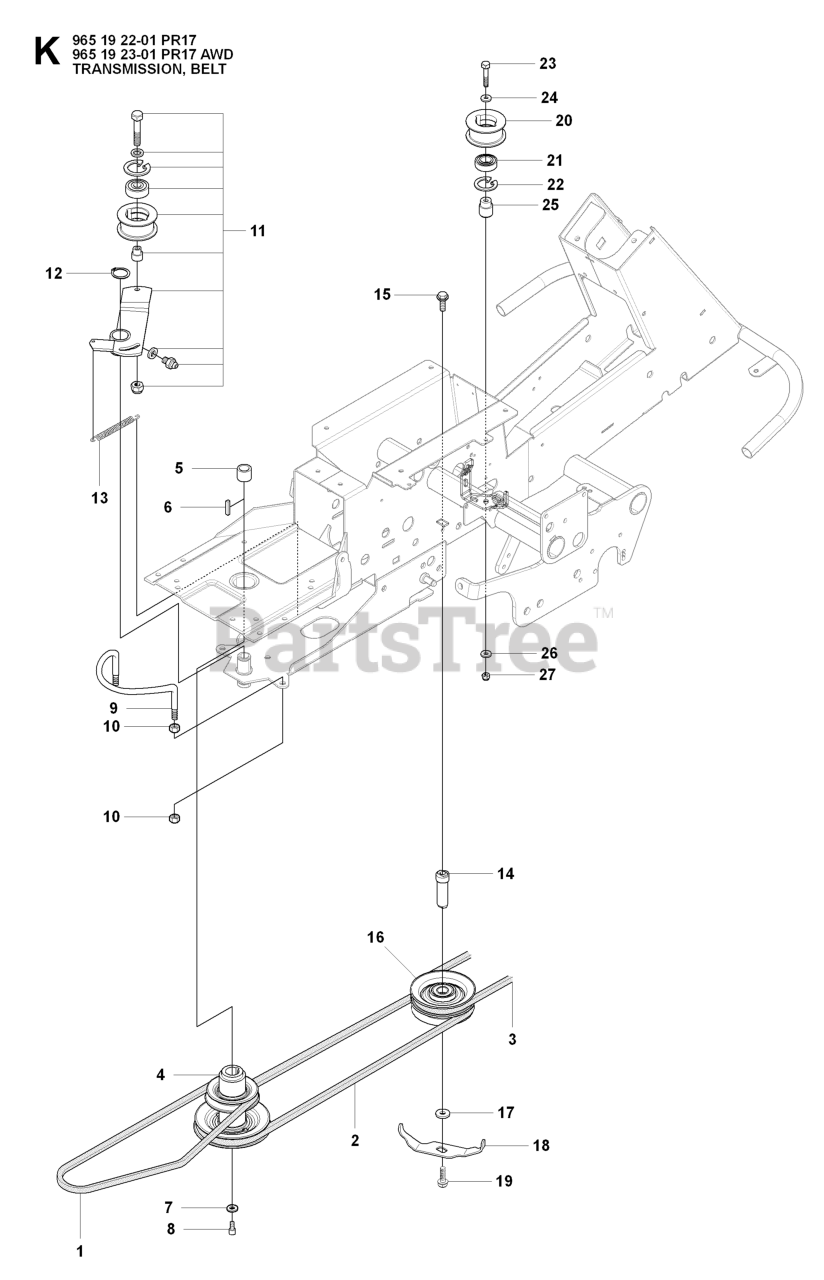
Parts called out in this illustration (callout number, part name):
1	BELT
3	BELT
9	BELT GUIDE
10	NUT
12	RETAINING RING SGA 25
18	BELT GUIDE
19	BOLT
20	%PULLEY
21	BALL BEARING 6004-2RS1
22	RETAINING RING
26	WASHER BRB 8.4X17
27	LOCKNUT M8
